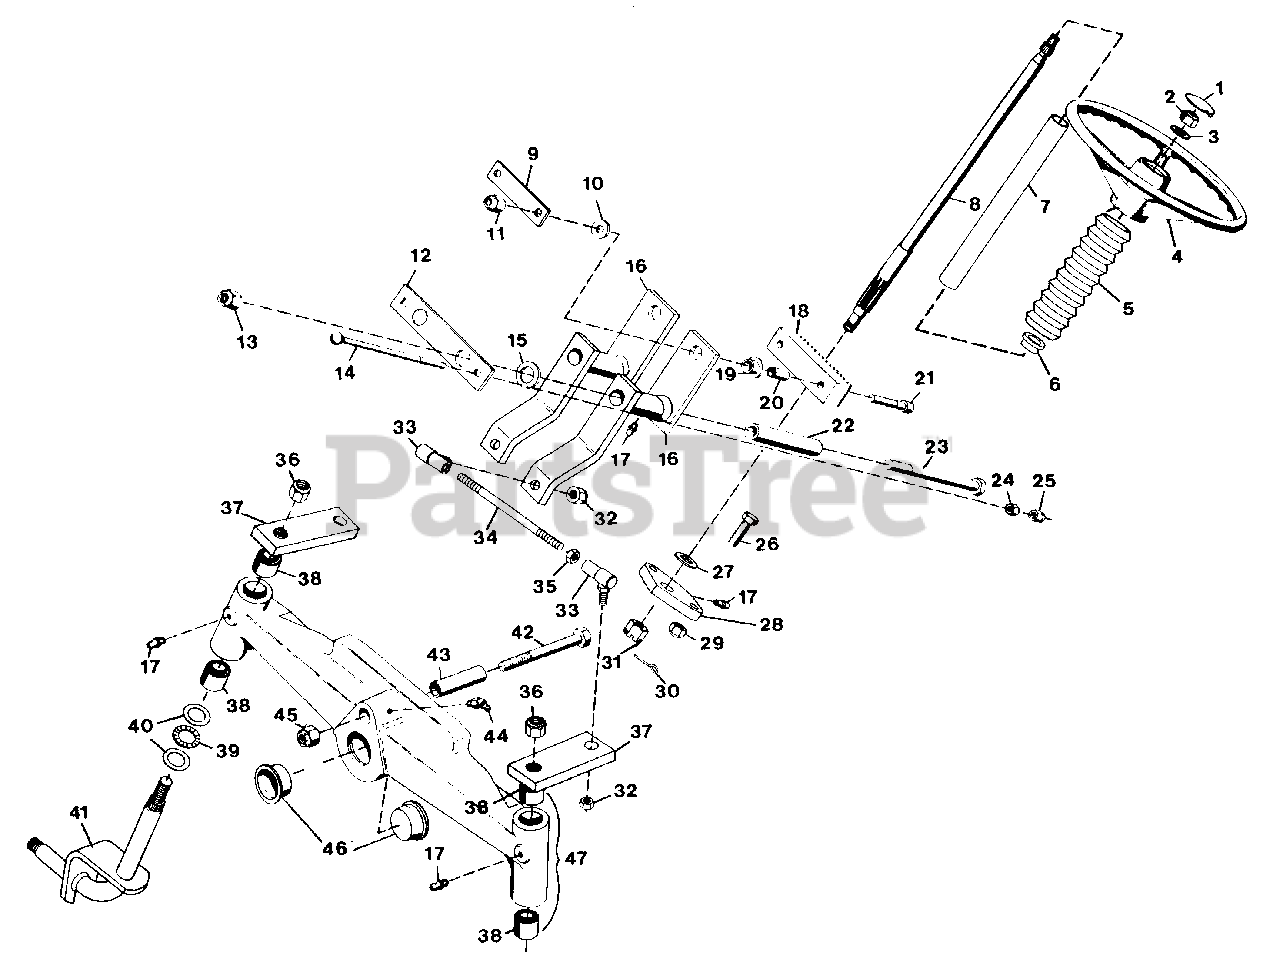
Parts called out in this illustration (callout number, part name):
1	CAP, STEERING WHEEL
2	NUT, JAM 5/8-11 HEX
3	WASHER, FLAT .656X1.312X.095
4	WHEEL, STEERING 8122
4	WHEEL, STEERING 8123 AND 8163-B
5	BELLOWS, STEERING WHEEL
6	BUSHING, NYLON .760X1.00X.60 FLG
7	TUBE, PLASTIC 1.0 I.D.
8	SHAFT, STEERING
9	STRAP, RACK AND PINION
10	WASHER, FLAT .375X1.125X.065
11	NUT, LOCK 3/8-16
12	PLATE, ADJUSTMENT
13	NUT, LOCK 1/2-13
14	BOLT, 5/16-18X5.5 RD HD SQ NK
15	RACE, BRG THRUST .752X1.240X.095
16	WELDMENT, STEERING
17	FITTING, LUBE 1/4-28
18	GEAR, RACK
19	BEARING, FLANGE(P/M BRONZE)
20	BUSHING, .391X.622X.670
21	SCREW, CAP 3/8-16X2.0 HSHD
22	SLEEVE, PIVOT
23	BOLT, HEX 1/2-13X6.0
24	NUT, HEX 5/16-18
25	NUT, LOCK 5/16-18
26	BOLT, HEX 7/16-14X1.5
27	RACE, THRUST
28	SUPPORT, STEERING SHAFT
29	NUT, LOCK 7/16-14
30	PIN, COTTER .09X1.00
31	NUT, HEX 1/2-13 SLOTTED
32	NUT, LOCK 3/8-24
33	BALL JOINT, STEERING
34	ROD, STEERING
35	NUT, HEX 3/8-24
36	NUT, HEX 5/8-11
37	ARM, TIE ROD AXLE
38	BUSHING, .877X1.004X1.0
39	BEARING, NEEDLE THRUST
40	RACE, BEARING THRUST
41	WELDMENT, KING PIN
42	BOLT, HEX 3/4-10X4.5
43	TUBE, AXLE PIVOT
44	FITTING, LUBE 45 DEG.
45	NUT, LOCK 3/4-10
46	CAP, FRONT AXLE
47	AXLE, STEERING
